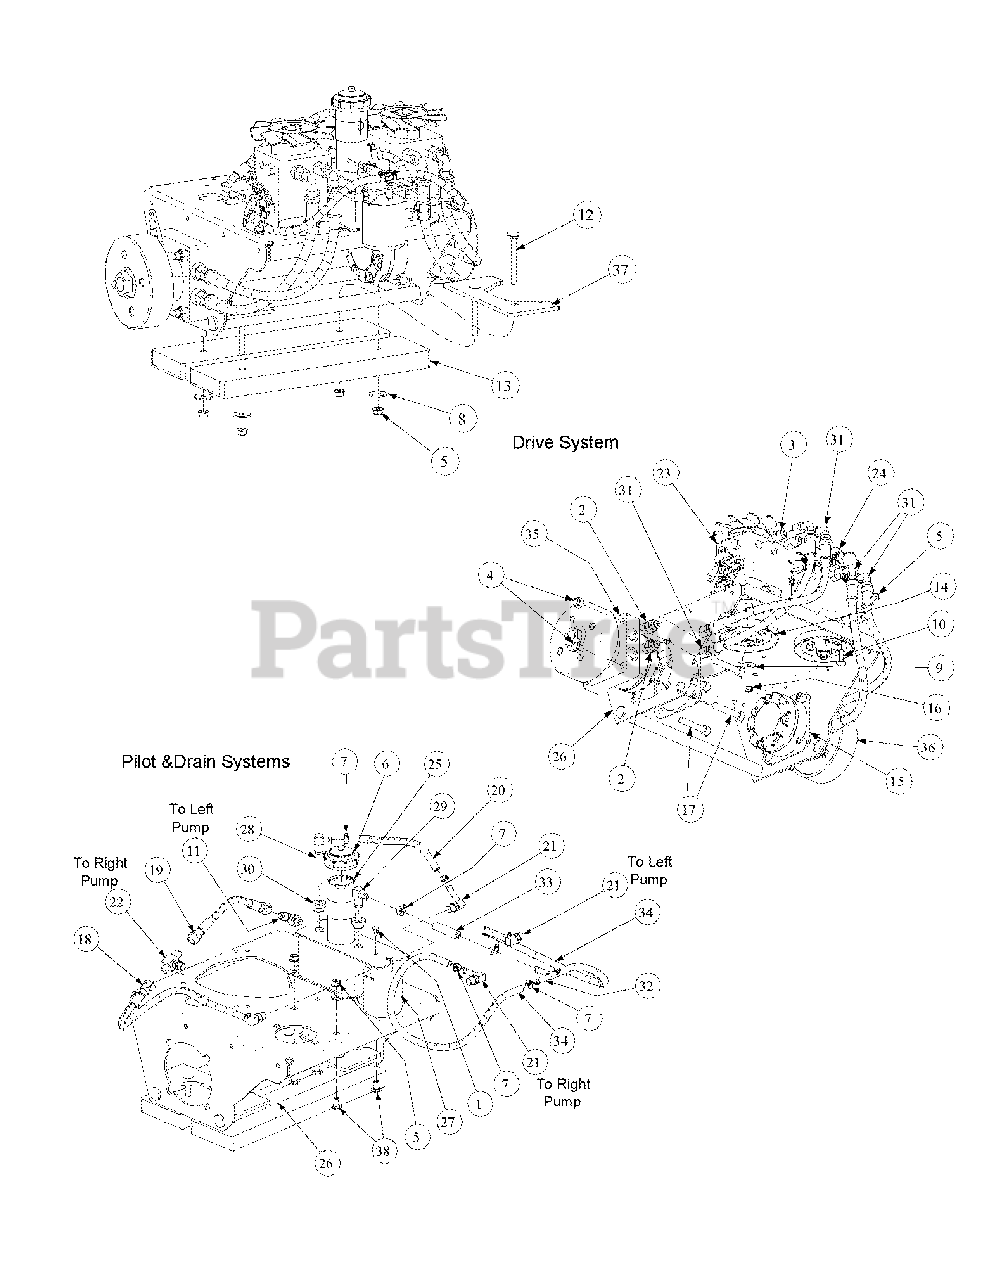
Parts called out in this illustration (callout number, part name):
1	Hex Cap Screw, 1/4-20 x 1/2
2	Fitting 1/2 x 3/4 - O Ring
3	Fitting 1/2 x 3/4 - O Ring to Flare
4	Lock Nut, Nylon Insert, 1/2-13
5	Flange Lock Hex Nut, 3/8-16
6	Cap, Hydro Oil Tank
7	Hose Clamp
8	Flat Washer, .411 x 1.25 x .100
9	Bell Washer, .396 x 1.14 x .095
10	Carriage Screw, 3/8-16 x 1.25
11	Elbow Fitting, 3/8 x 3/8
12	Carriage Bolt, 3/8-16 x 3.5 Lg
14	Hydro Pulley Pump
15	Motor Plate
16	Hex Nut, 3/8-24
17	Socket Head Capscrew, 1/2-13; 2-3/4
18	Hose Assembly Inlet Pump
19	Hose Assembly Inlet Connector
20	Drain Hose, 3/8
21	Fitting, 90 Degree O-Ring
22	Tee Fitting, O-Ring
23	Hydro Pump. RH
24	Hydro Pump, LH
25	Hydro Tank Weldment
26	Engine Mount Weldment
27	Filter Head 1/2
28	Elbow Fitting, Tube Steel
29	Elbow Fitting, w/o Tube Steel
30	Grommet Fitting, .54 ID x .78 OD
31	Pressure Hose Assembly
32	Tee Fitting
33	Hose, 3/8
34	Hose, 3/8
35	Hyd. Motor, White Right Hand
36	Hyd. Motor, White Left Hand
37	Deck Plate
38	Carriage Bolt, 3/8-16 x 0.75
